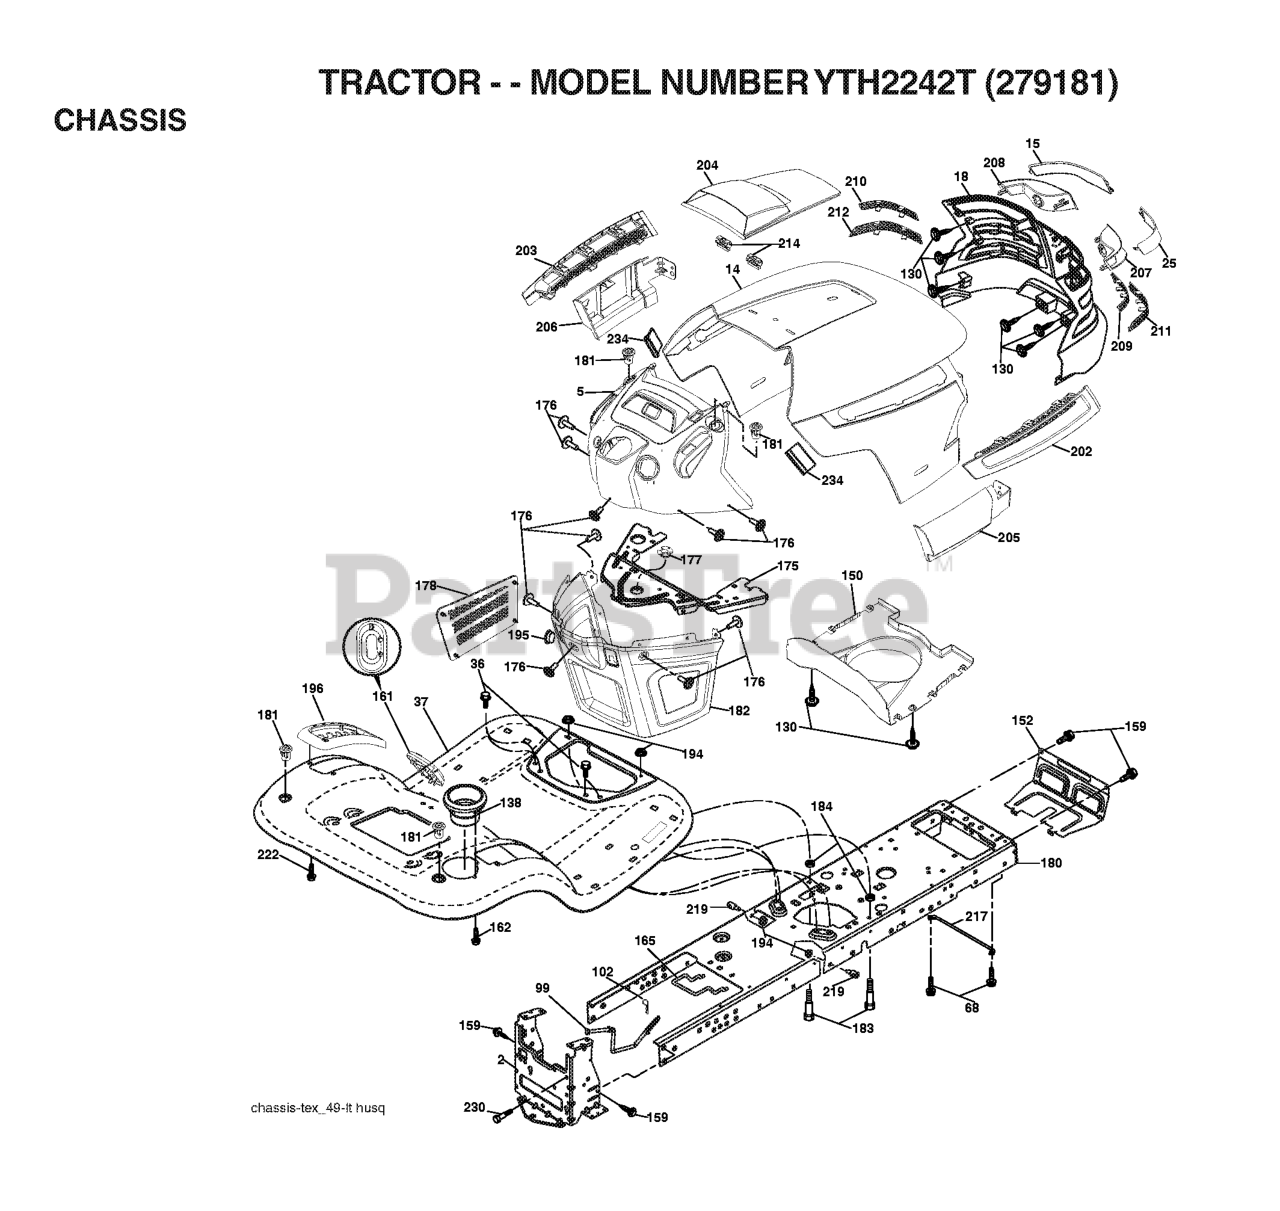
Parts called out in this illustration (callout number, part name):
2	DRAWBAR.1PC.NSTL
5	DASH.HUSQ.UPR.ELE.SVMD
14	HOOD.PNT.HUSQVARNA.GT.
15	LENS.LH.TEX.GT.HUSQ.CL
18	GRILLE.ASM.TX.GT.HUSQ
25	LENS.RH.TEX.GT.HUSQ.CL
36	SCREW 5/16"
68	Screw 5/16-18 x 1/2 Hex, Self Tapping 5/16-18 x 1/2
99	ROD ASM BYPASS
102	RETAINER M
130	SCREW
138	CUPHOLDER.TL.TEX.418
150	AIR.DUCT.TEXGT.HUSQ.SV
152	SHIELD.BROWNING/DEBRIS
159	SCREW, 3/8-16X3/4
161	RP WINDOW.FUEL.LT.TEX.GREY
162	SCREW.HI-LO.CONSOLE
165	SUPPORT.TANK.REAR.WIRE
175	PLATE.CROSSMEMBER.HUSQ
176	SCREW.#10-24X5/8.RN.QU
177	BUSHING, STEERING
178	CARGO.ASM.NET.TXGT.W/C
180	CHASSIS.STAMPING.LT/GT
181	BUSHING.MNT.FEND.CRGO.
182	DASH.LOWER.COMMON.12V.
183	BOLT.5/16-18X1-1/4 FULL.THREAD
184	SPACER.FENDER
194	NUT LOCK HEX FLANGE 5/16-18
195	PLUG.HOLE.DASH.LOWER.12V.BLK
196	CONSOLE.ASM.DECK.LIFT.
202	VENT.SIDE.HOOD.HUSQ.RH.GREY
203	VENT.SIDE.HOOD.HUSQ.LH.GRAY
204	VENT.TOP.HOOD.HUSQVARN
205	SKIRT.HOOD.SIDE.HUSQ.RH.GREY
206	SKIRT.HOOD.SIDE.HUSQ.LH.GREY
207	BEZEL.RH.TEX.GT.HUSQ
208	BEZEL.LH.TEX.GT.HUSQ
209	INSERT.HEX.GRILL.HUSQ.GREY
210	INSERT.HEX.GRILL.HUSQ.
211	INSERT.HEX.GRILL.HUSQ.
212	INSERT.HEX.GRILL.HUSQ.
214	CLIP.RETAINER.TINNER.
217	ROD PIVOT CHASSIS/HOOD
219	STUD.FASTNER.W/ANTI-ROTATE
222	SCREW.1/4-20X5/8
230	SHOULDER BOLT 5/16-18TT
